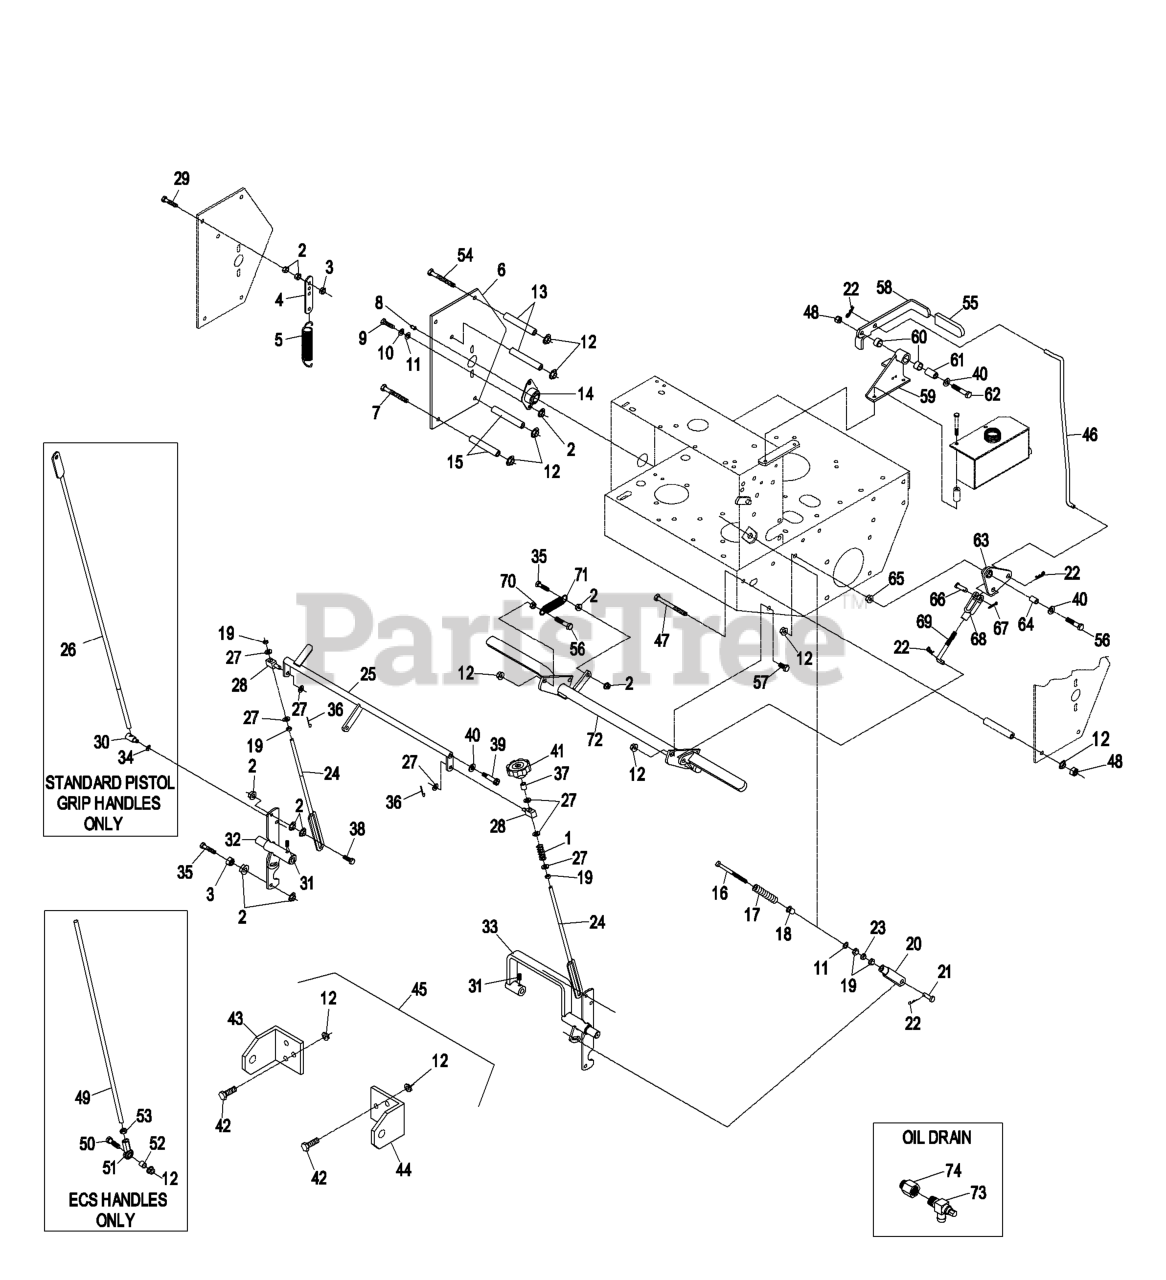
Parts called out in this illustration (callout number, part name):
1	SPRING-COMPRESSION
3	NUT-LOCK, NI
4	TAB-SPRING, EXTENSION
5	SPRING-EXTENSION
7	SCREW-HH
8	FITTING-GREASE
9	SCREW-HH
10	WASHER-LOCK
11	WASHER-FLAT
12	NUT-HHF, WHIZ
13	SPACER-SHIELD
14	BEARING-FLANGE, SIDE
15	SPACER-SHIELD
16	BOLT-RETURN, NEUTRAL
17	SPRING-RETURN, NEUTRAL
18	BUSHING-FLANGED
19	NUT-HEX
20	YOKE-ADJUSTABLE
21	PIN-CLEVIS
22	PIN-COTTER
23	NUT-JAM
24	LINK-CONTROL, SPEED
26	ROD-LEVER, DRIVE
27	WASHER-PLAIN
29	BOLT-TAP, HH
30	SWIVEL-LEVER, DRIVE
31	SCREW-SET
32	SHAFT-CONTROL, LH
34	RING-RETAINING
35	SCREW-HH
36	PIN-COTTER
38	SCREW-HH
39	SCREW-HSH
40	WASHER-FLAT
41	KNOB-TRACKING
42	SCREW-HH
44	BRACKET,SULKY RH
45	Sulky Kit
46	LINKAGE,UPPER- TTHP
47	SCREW-HH
48	NUT-LOCK, NI
49	LINK,DRIVE (PLTD)
50	SCREW-HH
51	JOINT-BALL END, LH
52	SPACER-TUBE, PUMP LINK
53	NUT-HEX JAM, LH
54	SCREW-HH
55	GRIP-LEVER
56	SCREW-HH
57	SCREW-HH
59	BRACKET ASM
60	SLEEVE-BUSHING
61	BUSHING-PIVOT
62	SCREW-HH
63	BELLCRANK ASM
64	BUSHING-PLASTIC
66	PIN-CLEVIS
67	PIN-COTTER
68	YOKE-LINKAGE, BRAKE
69	LINKAGE-LOWER
70	NUT-JAM
71	SPRING-IDLER
73	VALVE-DRAIN, OIL
74	ADAPTER
